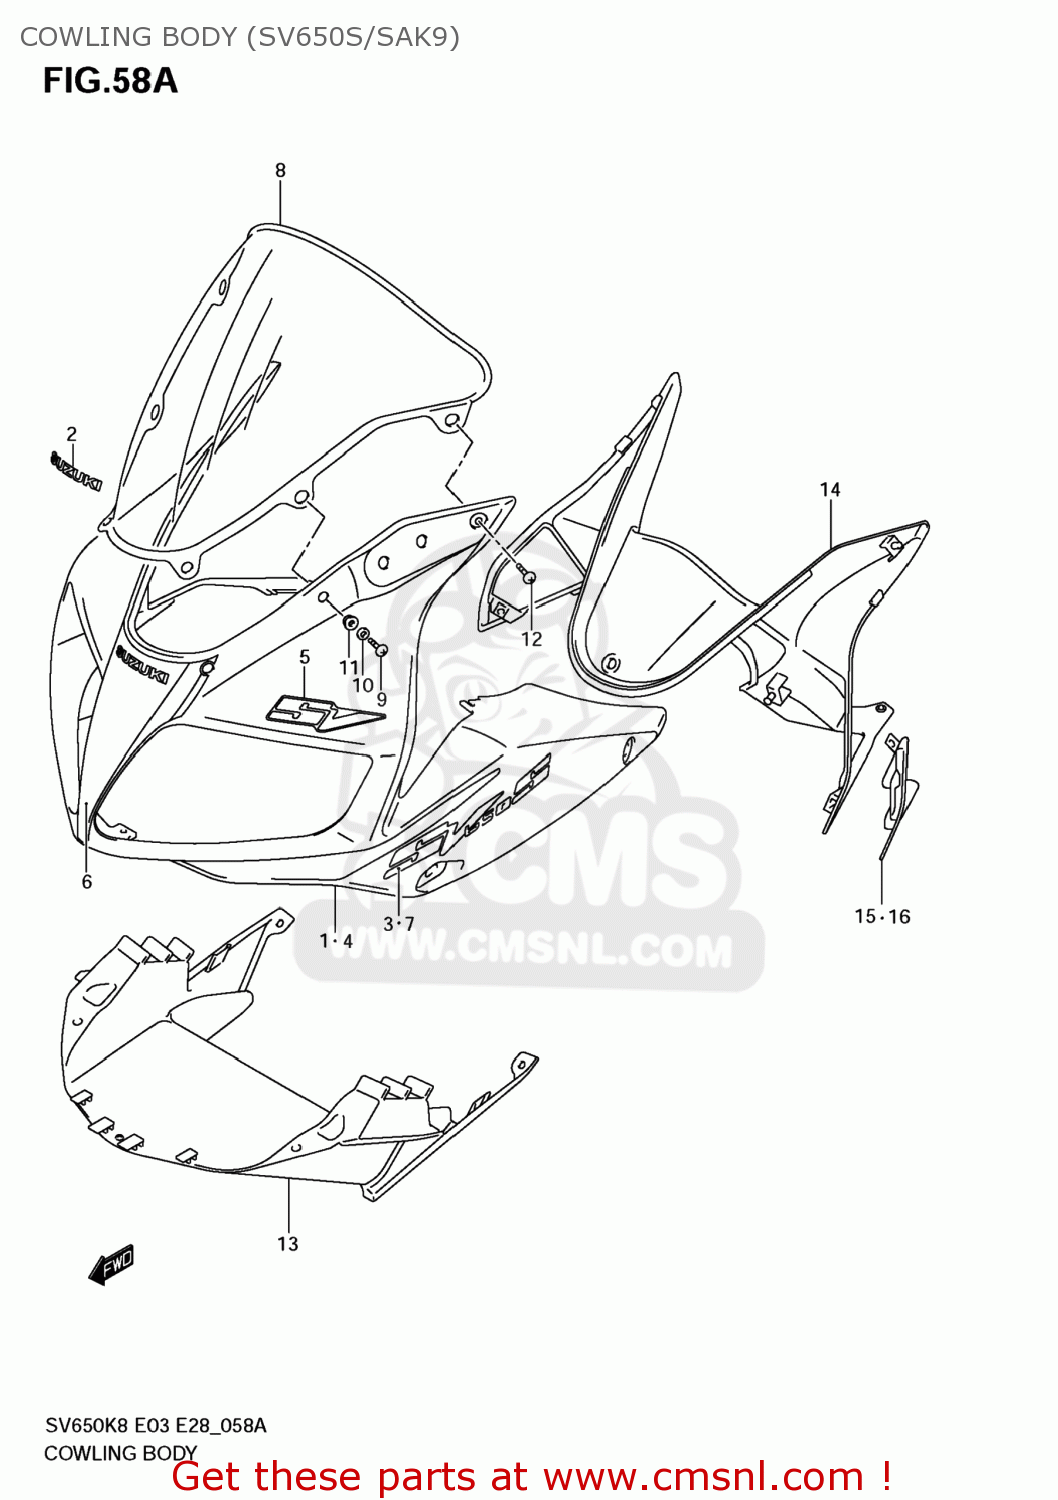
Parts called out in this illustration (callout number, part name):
1	COWLING ASSY,BODY
2	EMBLEM,SUZUKI
3	EMBLEM,BODY COWL
4	COWLING ASSY,BODY
5	EMBLEM,BODY COWL FR
6	TAPE,BODY COWL FR
7	EMBLEM,BODY COWL
8	WINDSCREEN
9	SCREW(5X14)
10	WASHER
11	NUT
12	SCREW(5X16)
13	COVER,COWLING INNER
14	PANEL,METER
15	LID,METER PANEL,R
16	LID,METER PANEL,L
